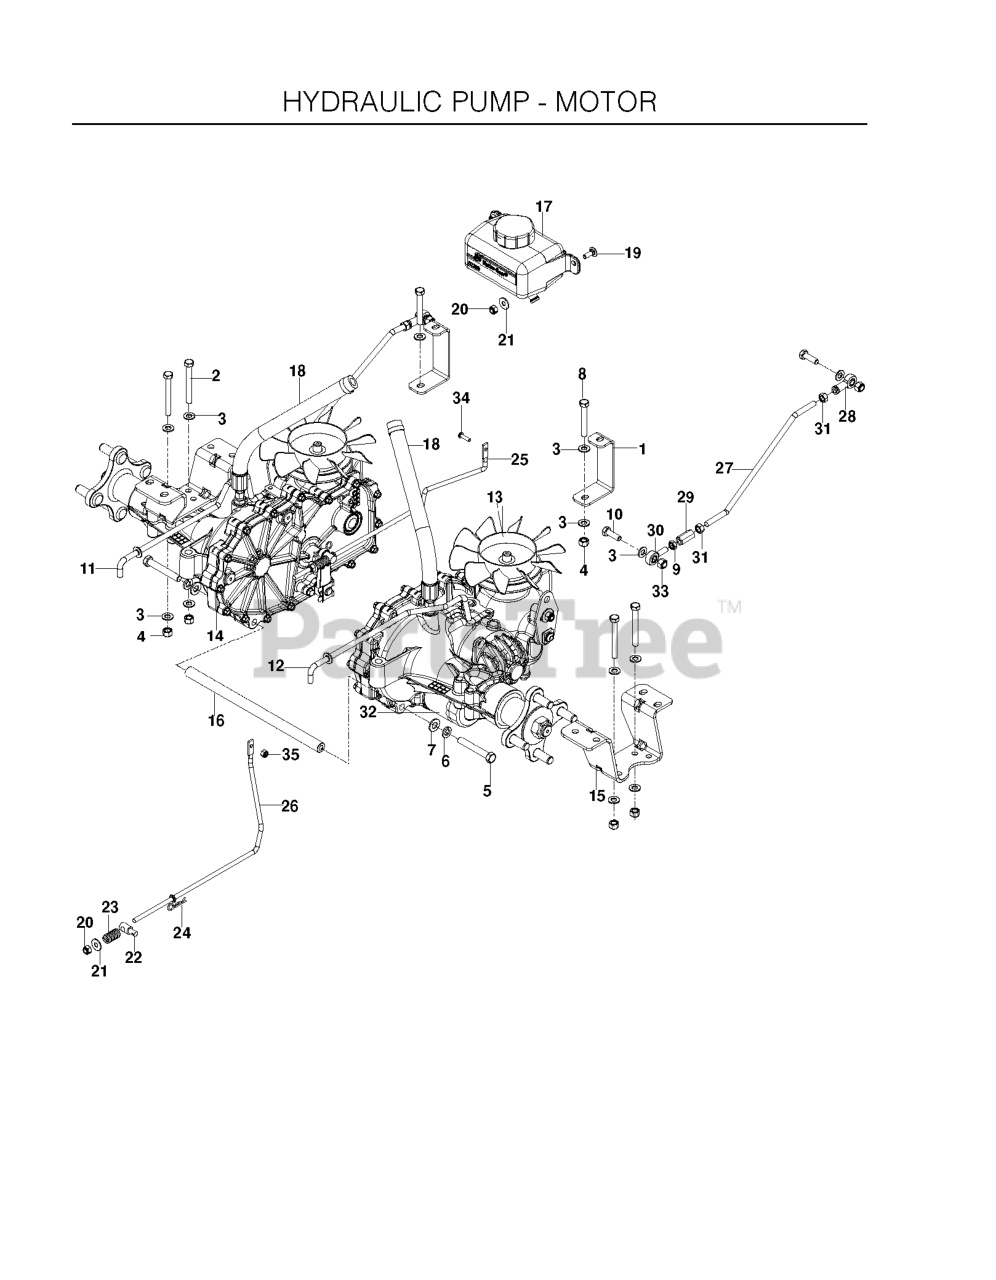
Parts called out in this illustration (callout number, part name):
1	SUPPORT.FRONT.TRANS.BLACK.
2	HCS 5/16C X 2-3/4
3	FLAT WASHER 5/16 SAE
4	NUT 5/16 NYLOC
5	HCS 3/8C X 2 1/2
6	SLW 3/8 STD
7	WASHER 3/8 SAE FLAT
9	NUT 5/16F LEFTHAND
10	HCS 5/16C X 1
11	ROD, BYPASS, RT
12	ROD, BYPASS, LT
13	HG_TRANS, ZT-2800 RT
14	HG_TRANS, ZT-2800 LEFT
15	EZT MOUNT, REAR, BLACK
16	SPACER TUBE, EZT, 11.08
17	HG_EXPANSION TANK W/CAP 71354
19	RHSNB 1/4C X 3/4
20	NUT.1/4-20.HEX.NYLOC.ZD
21	WASHER 1/4 FLAT
22	BRAKE SWIVEL
24	HAIRPIN #2
25	LINKAGE.BRAKE.LT
26	LINKAGE, BRAKE RT
27	ROD, MOTION CONTROL
28	RH ROD END
29	ROD END COUPLER
30	RP.ROD.END.LH
32	HG_FILTER, ZT4800 52114
33	5/16-18 THIN PROF NY
34	SCR #10-24 X 3/4
35	NUT 10-24 NYLOC
